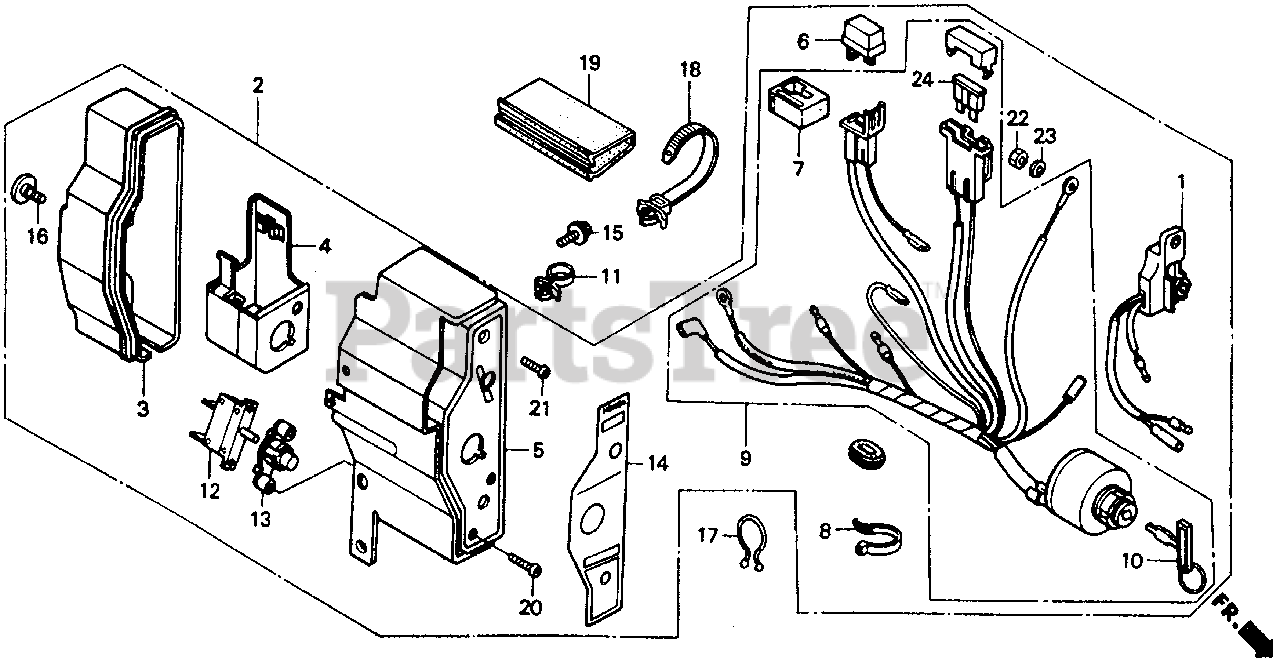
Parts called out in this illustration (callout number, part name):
1	ALERT UNIT, OIL (SEL)
2	BOX ASSY., CONTROL (EXTERNAL-ALERT)
2	BOX ASSY., CONTROL (3A) (EXTERNAL-ALERT)
3	CASE, CONTROL
4	BRACKET, CASE MOUNTING
5	PANEL, CONTROL *R8* (BRIGHT RED)
6	RECTIFIER ASSY., SILICON (STANLEY)
7	SUSPENSION, CONNECTOR
8	BAND
9	SWITCH ASSY., COMBINATION
10	KEY
11	HOLDER, STOP SWITCH WIRE
12	PROTECTOR, CIRCUIT (1.0A)
12	PROTECTOR, CIRCUIT (3.5A)
13	LENS ASSY., PROTECTOR
14	PANEL, CONTROL BOX (EXTERNAL-ALERT)
15	BOLT, FLANGE (6X12) (CT200)
16	SCREW, SPECIAL (6X12)
17	CLIP, PURSE LOCK
18	STRAP, CABLE (118MM) *NH1L* (BLACK)
19	TUBE, FASTENER (30)
20	SCREW, PAN (3X12)
21	SCREW, PAN (4X12)
22	NUT, HEX. (4MM)
23	WASHER, SPRING (4MM)
24	FUSE, BLADE (5A)
24	FUSE, BLADE (15A)
